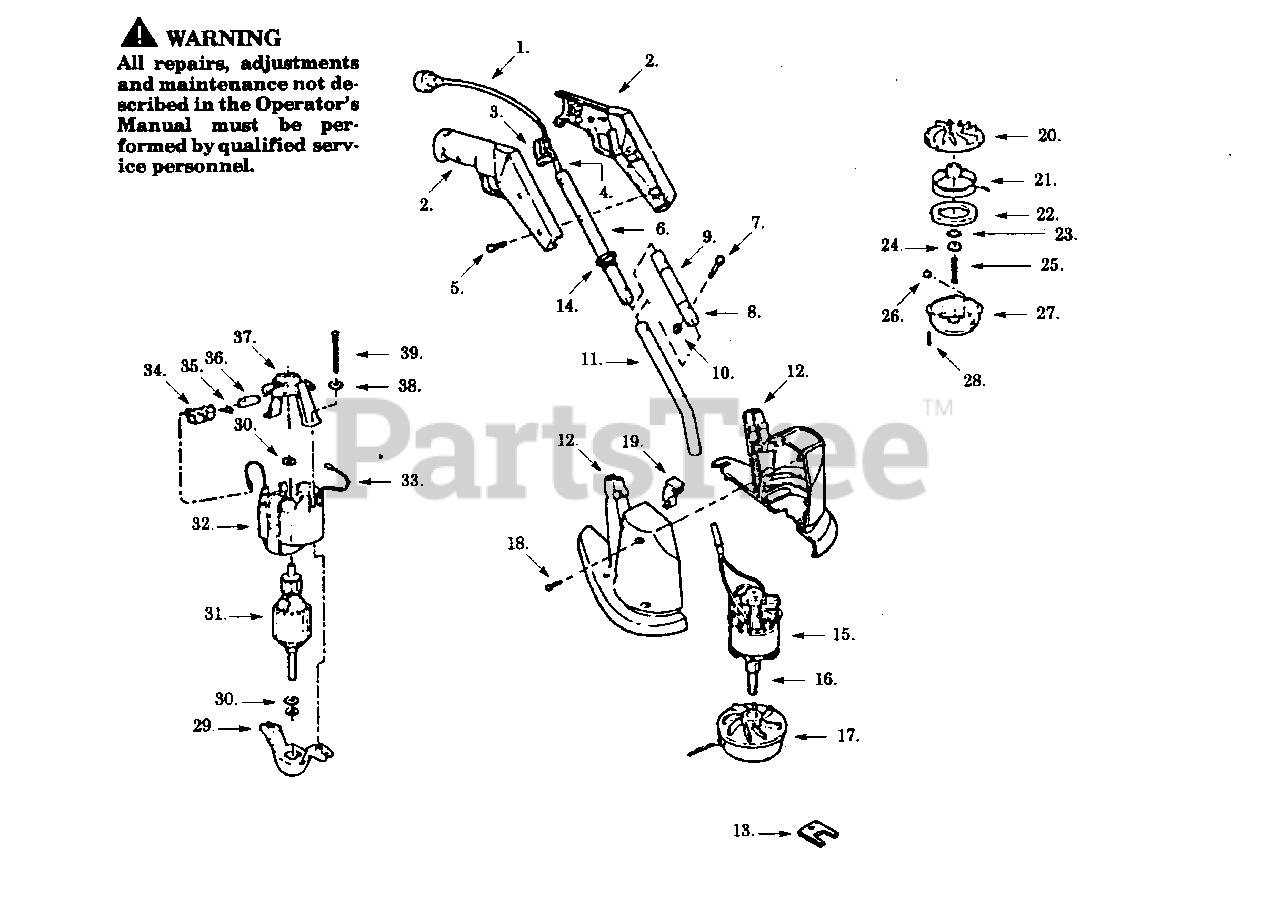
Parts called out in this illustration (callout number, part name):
1	Power Cord
2	Handle Set
3	Trigger Switch
6	Upper Tube
8	Outer Tube
9	Warning Label (Not a serviceable part)
11	Lower Tube
12	Housing Set
13	Spanner Wrench
16	Shaft Adapter
17	Auto Head Ass'y.
19	Blade Retainer Ass'y.
20	Rear Plate
21	Spool & Line
22	Foam Pad
24	Adapter Nut
27	Hub Ass'y.
28	Cotter Pin
29	Endbell Ass'y. (Drive)
31	Armature Ass'y.
32	Field Ass'y.
33	Lead Wire Ass'y.
34	Brush Holder Ass'y.
35	Brush Spring
37	Endbell Ass'y. (Brush)
38	Lockwasher
